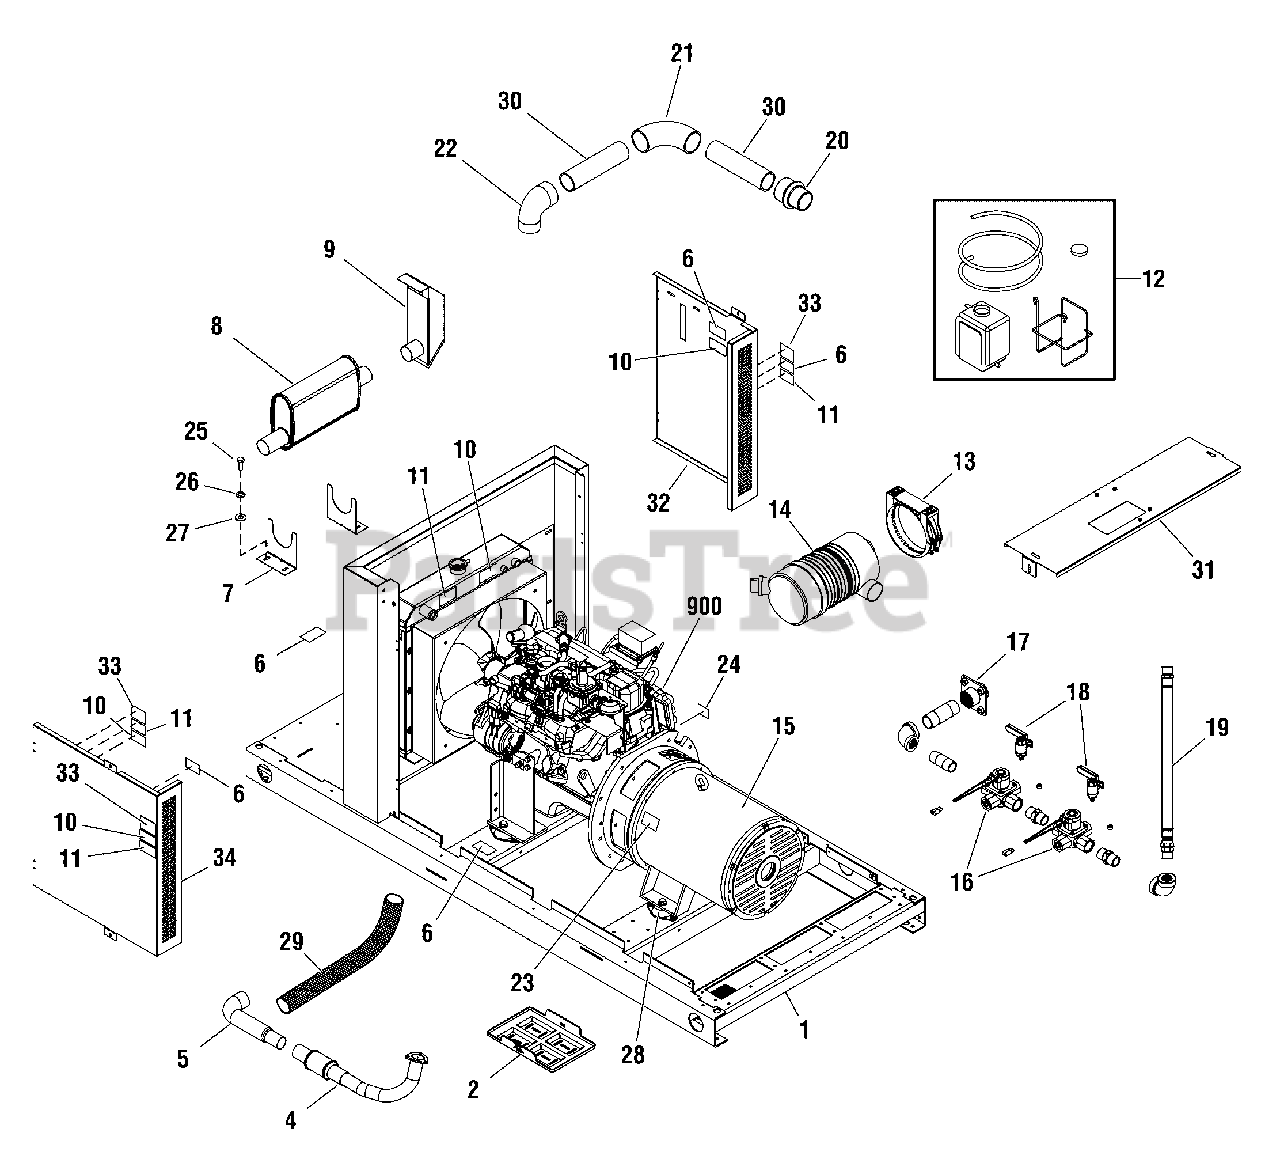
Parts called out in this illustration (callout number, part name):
1	BASE
6	DECAL
7	BRACKET, Muffler
8	MUFFLER
9	DIFFUSER
11	DECAL
12	BOTTLE, Overflow
16	VALVE, Fuel
20	REDUCER
24	DECAL
25	* CAPSCREW, Hex Head, HHCS-1/4-20 x 3/4
26	* WASHER, Lock, 1/4-M6
27	* WASHER, Flat, 1/4
28	MOUNT, Vibration
33	DECAL
900	** ENGINE
